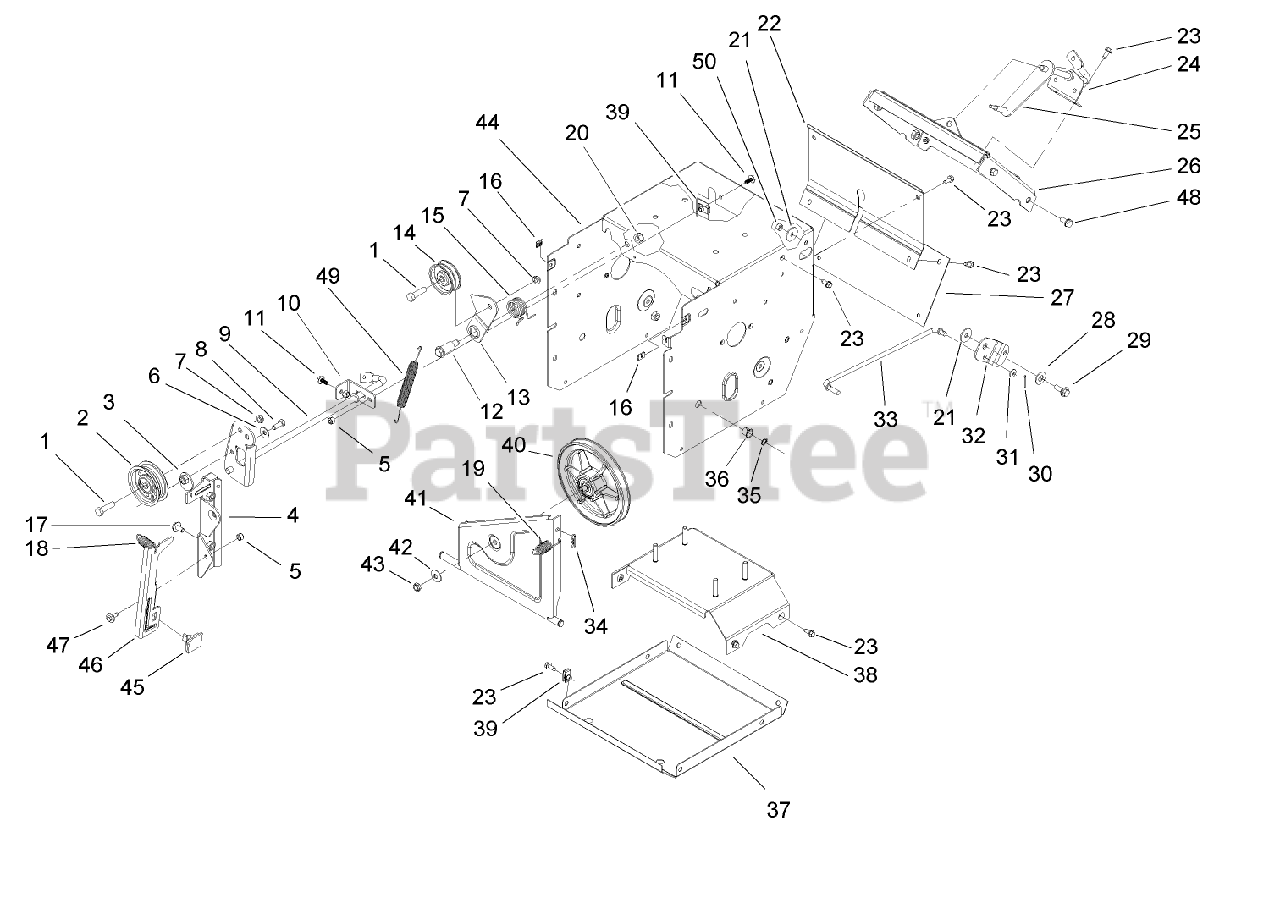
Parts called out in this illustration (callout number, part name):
1	SCREW-HH
2	PULLEY-IDLER
5	NUT-LOCK, NI
6	WASHER-BELLEVILLE
8	SCREW-HH
9	IMPELLER CLUTCH ASM
10	BRACKET-REAR, CLUTCH
11	SCREW-HHF
12	BOLT-SHOULDER
13	ARM-IDLER, TRACTION
14	PULLEY-IDLER
16	NUT-SPEED
17	SCREW-HHF
18	SPRING-EXTENSION
19	SPRING-EXTENSION
20	NUT-LOCK, NI
21	WASHER-PIVOT
22	COVER-UPPER
23	SCREW-HWH
24	BRACKET-ROD, SHIFT
25	LEVER-CONTROL, TRACTION
26	SHIFT PLATE ASM
27	COVER-LOWER
28	WASHER
29	SCREW-SHOULDER
30	PIN-COTTER
31	WASHER-PLAIN
32	BELLCRANK-DRIVE
33	LINK-CONTROL, SPEED
35	RING-RETAINING
36	BUSHING-NYLINER
37	PAN-BOTTOM
40	PULLEY-TRACTION
42	WASHER-BELLEVILLE
43	NUT-HEX
44	TRACTION FRAME ASM
45	PAD-BRAKE
47	SCREW-SHOULDER
48	SCREW-HWHTF
50	NUT-LOCK, NI
